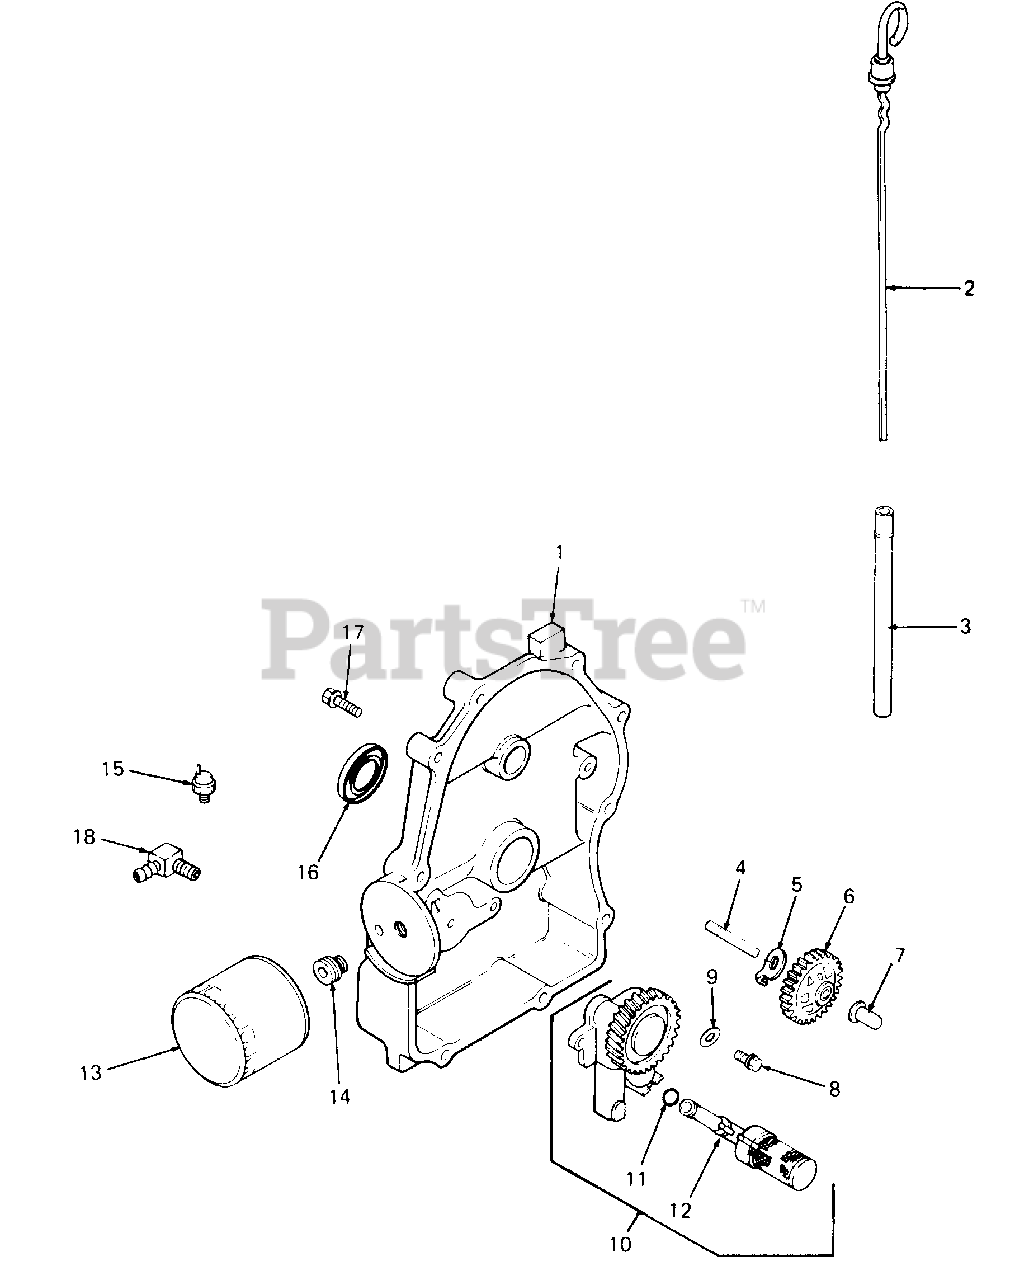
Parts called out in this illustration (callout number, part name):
1	Plate, Closure
2	Dipstick
3	Tube, Dipstick
4	Shaft, Governor Gear
5	Tab, Locking
6	Governor Gear Assembly
7	Pin, Governor Regulating
8	Screw
9	Washer
10	Oil Pump Assembly
11	O-Ring, Oil Pick-Up
12	Pick-Up, Oil
13	Filter, Oil
14	Adapter, Oil Filter
15	Switch, Oil Pressure
16	Seal, Oil (PTO end)
17	Screw, Closure Plate, M8 X 10 1.25 X 45
18	Connector, 90ø Hose
